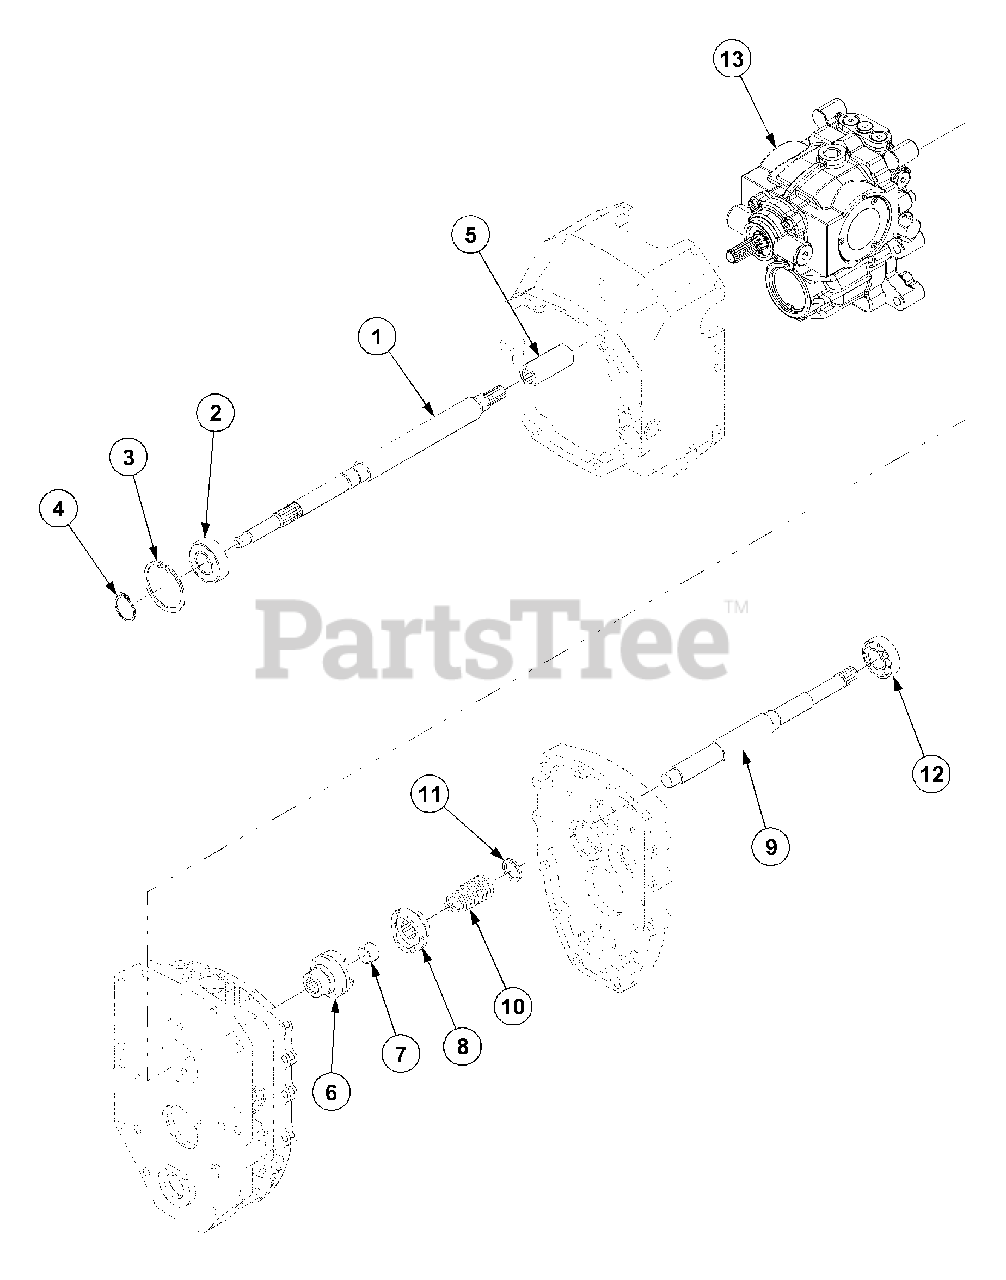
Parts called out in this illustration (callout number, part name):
1	Shaft,Drive
3	C-Ring
4	C-Ring
12	Bearing,Ball
